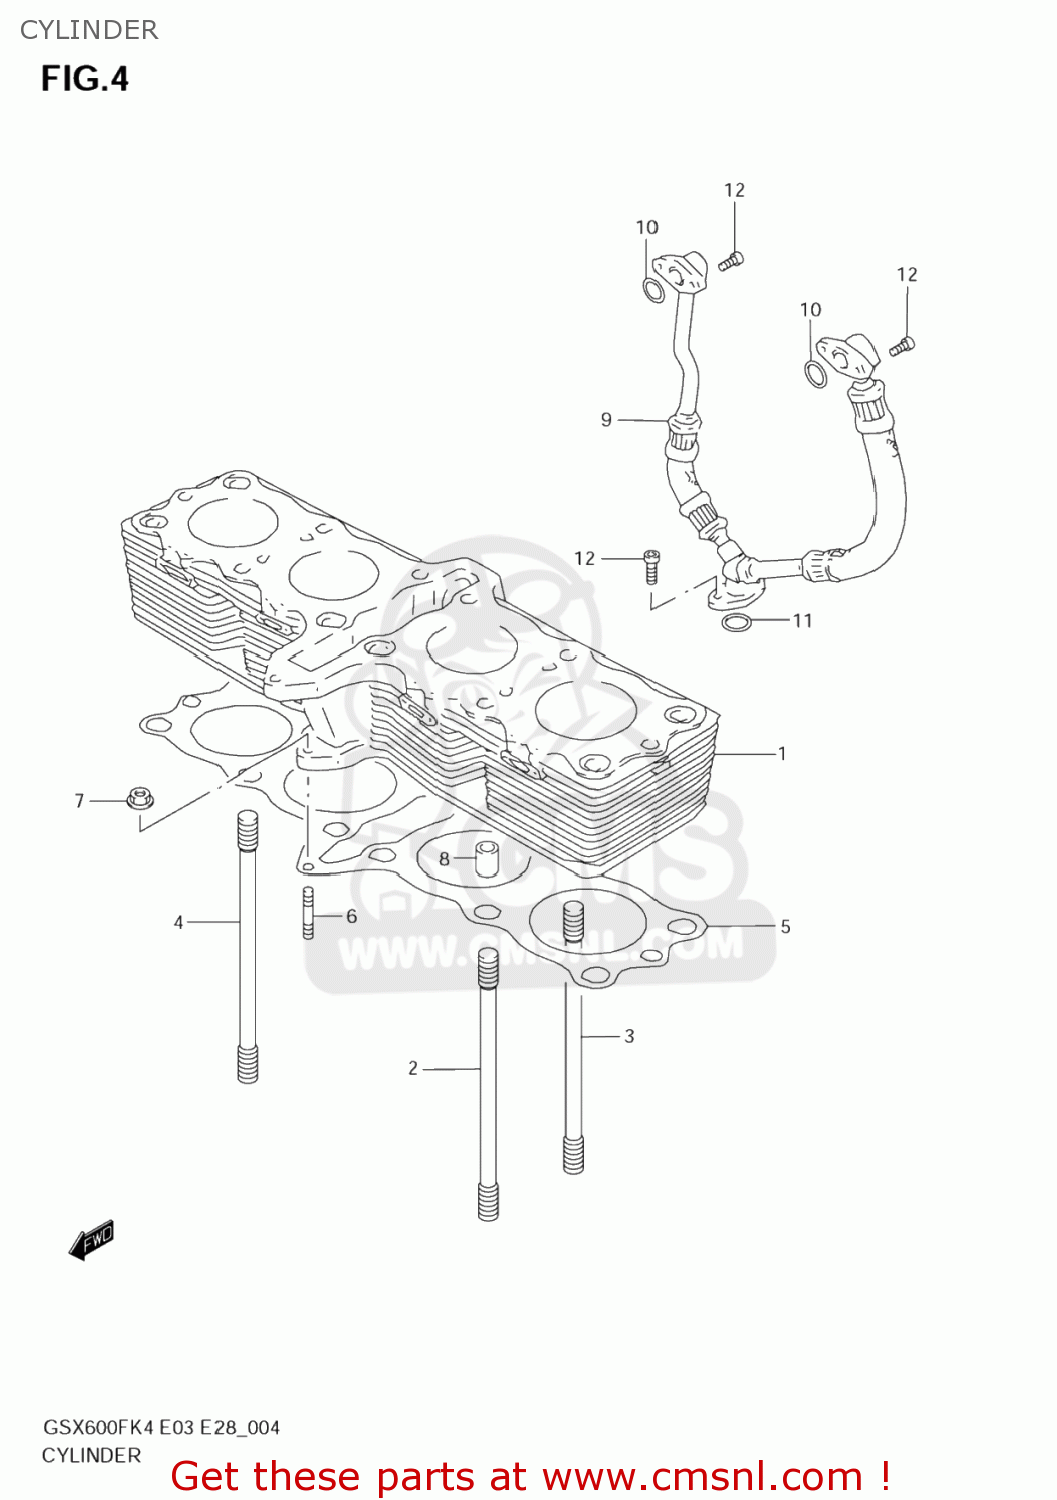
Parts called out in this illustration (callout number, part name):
1	CYLINDER
2	BOLT,STUD
3	BOLT,STUD
4	BOLT,STUD
5	GASKET,CYLINDER (NAS)
6	STUD,M6X1X32
7	NUT
8	PIN(13X10.4X20)
9	HOSE,OIL HEAD COOLER
10	O RING(D:2.5,ID:13.8)
11	O RING(D:2.4,ID:15.8)
12	BOLT,OIL FILLE
